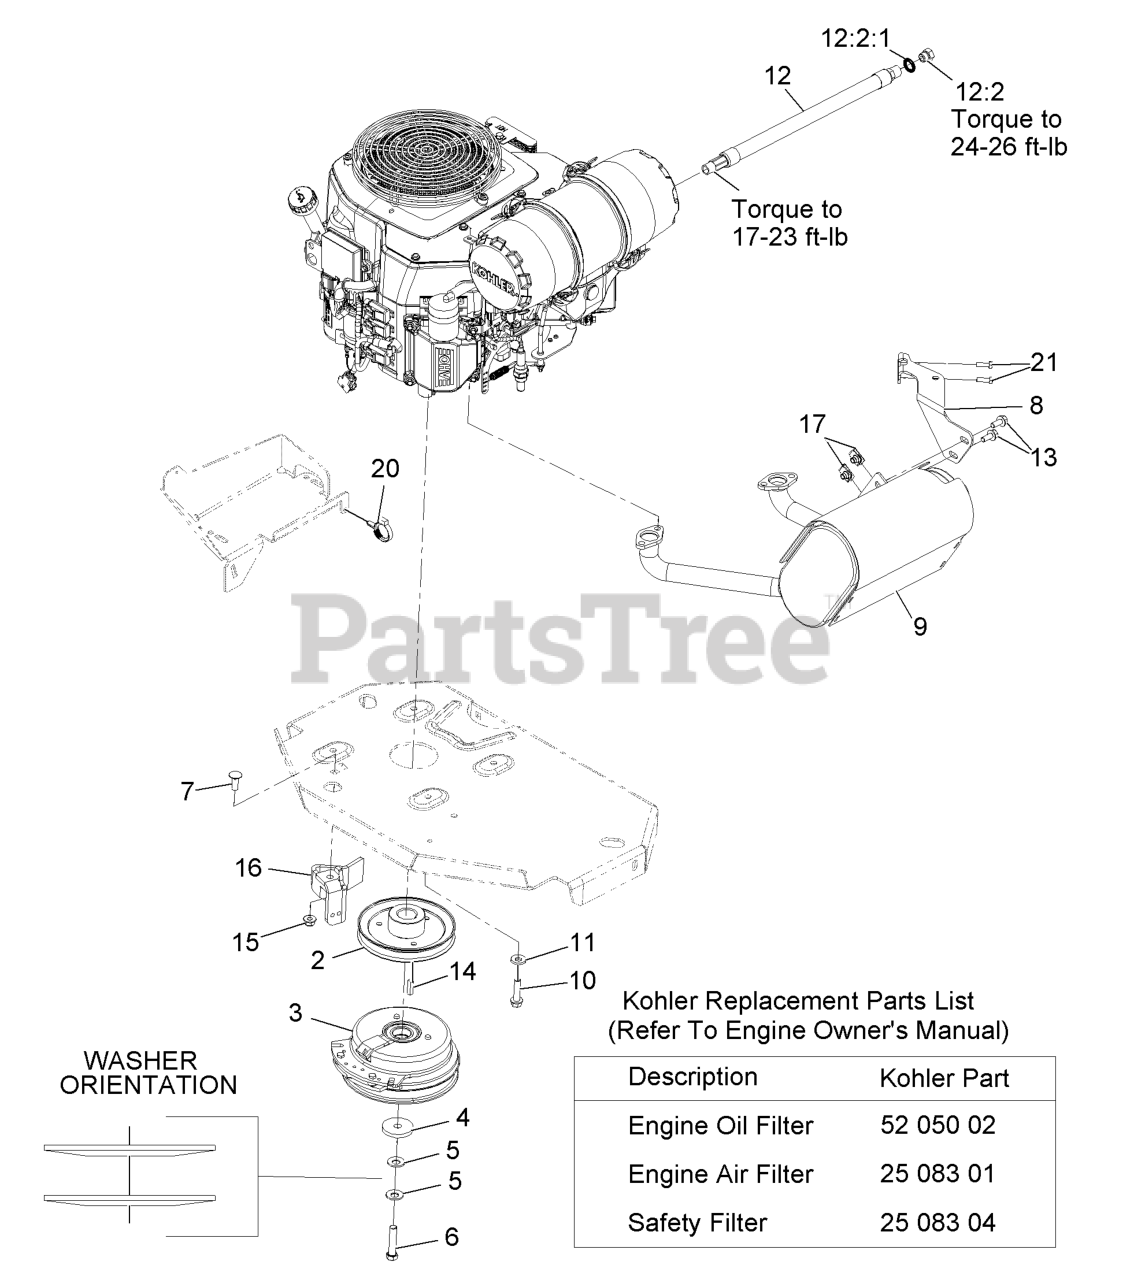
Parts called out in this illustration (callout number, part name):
2	SHEAVE
3	CLUTCH KIT
4	WASHER-CLUTCH
5	WASHER-SPRING
6	SCREW-HH W/LOCTITE
7	SCREW-CARR
8	MUFFLER BRACKET KIT
10	SCREW-HWH
11	WASHER-BELLEVILLE
12	OIL DRAIN HOSE ASM
12:2	PLUG-HH
12:2:1	O-RING
13	SCREW-HHF
15	NUT-HF, NI
16	CLUTCH-ANCHOR
20	CLAMP-HOSE
21	SCREW-HH M6-1 X 20Mm W/Patch
